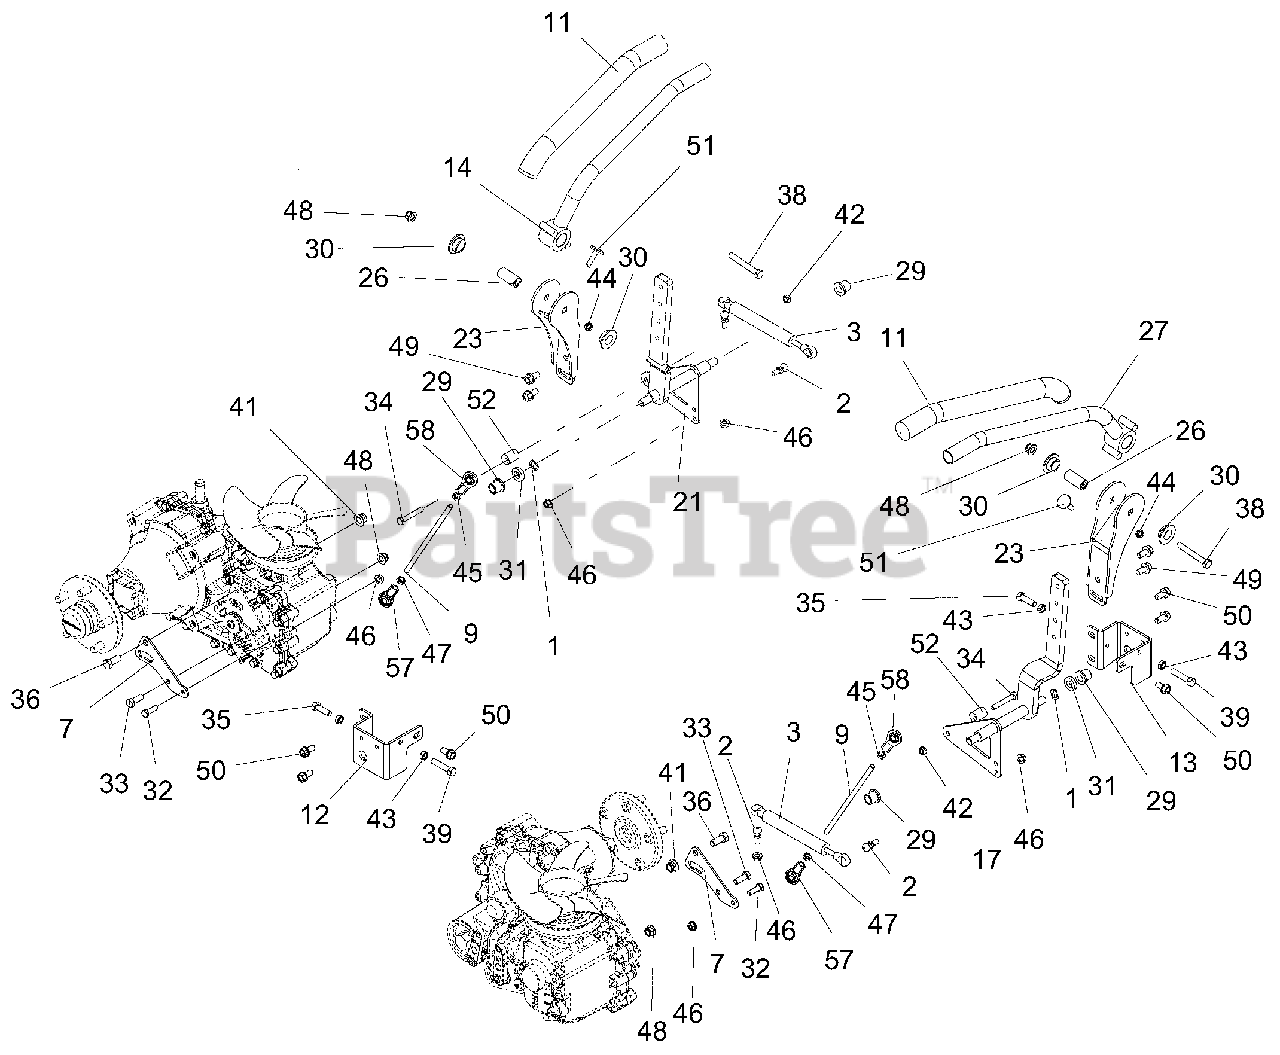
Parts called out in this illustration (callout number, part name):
1	WAVE WASHER .531X.781X.125 FH
2	STUD-BALL
3	DAMPER
7	BRKT., CONTROL MTG
9	ROD, STEERING
11	GRIP, HANDLEBAR
12	BRKT, RH CONTROL ARM STOP
13	BRKT, LH CONTROL ARM STOP
14	WLDMT, RH STEERING ARM
17	WLDMT, LH LOWER CONTROL ARM
21	WLDMT, RH LOWER CONTROL ARM
23	MOUNT, STEERING ARM, ADJUSTABLE
26	SPCR, STEERING ARM
27	WLDMT, LH STEERING ARM
29	BUSHING, PLASTIC
30	BUSHING, FLANGE
32	BLT-HEX .31-18X1.00 GR5 YWZC
33	BLT-HEX .38-16X1.00 GR5
34	BLT-HEX .31-18X2.00 GR5 YWZC
35	BLT-HEX .38-16X1.25 GR5 YWZC
36	BLT-HEX .44-14X1.00 GR5
38	BLT-RDHDSQSHK, 38-16X2.50 G5YZ
39	BLT-HEX .38-16X1.75 GR5 FTD YWZ
41	NUT-LK-NYL-FLG .44-14 YWZC
42	NUT-LK-CTR .31-18 YWZC
43	NUT, 3/8-16 JAM GR5
44	NUT, 5/16-18 JAM GR5
45	NUT-JAM
46	NUT, LK-TOP-FLG .312-18 YWZC
47	NUT, JAM -LH .31-24 YWZC
48	NUT-LK-NYL-FLG .38-16 YWZC
49	BLT-SERHFWH .38-16X.75 YWZC
50	SCR-TAP .38-16X.75 HWH TR YWZ
51	BUMPER, STUD MOUNTED
52	ECCENTRIC
57	LH ROD END
58	RH ROD END
